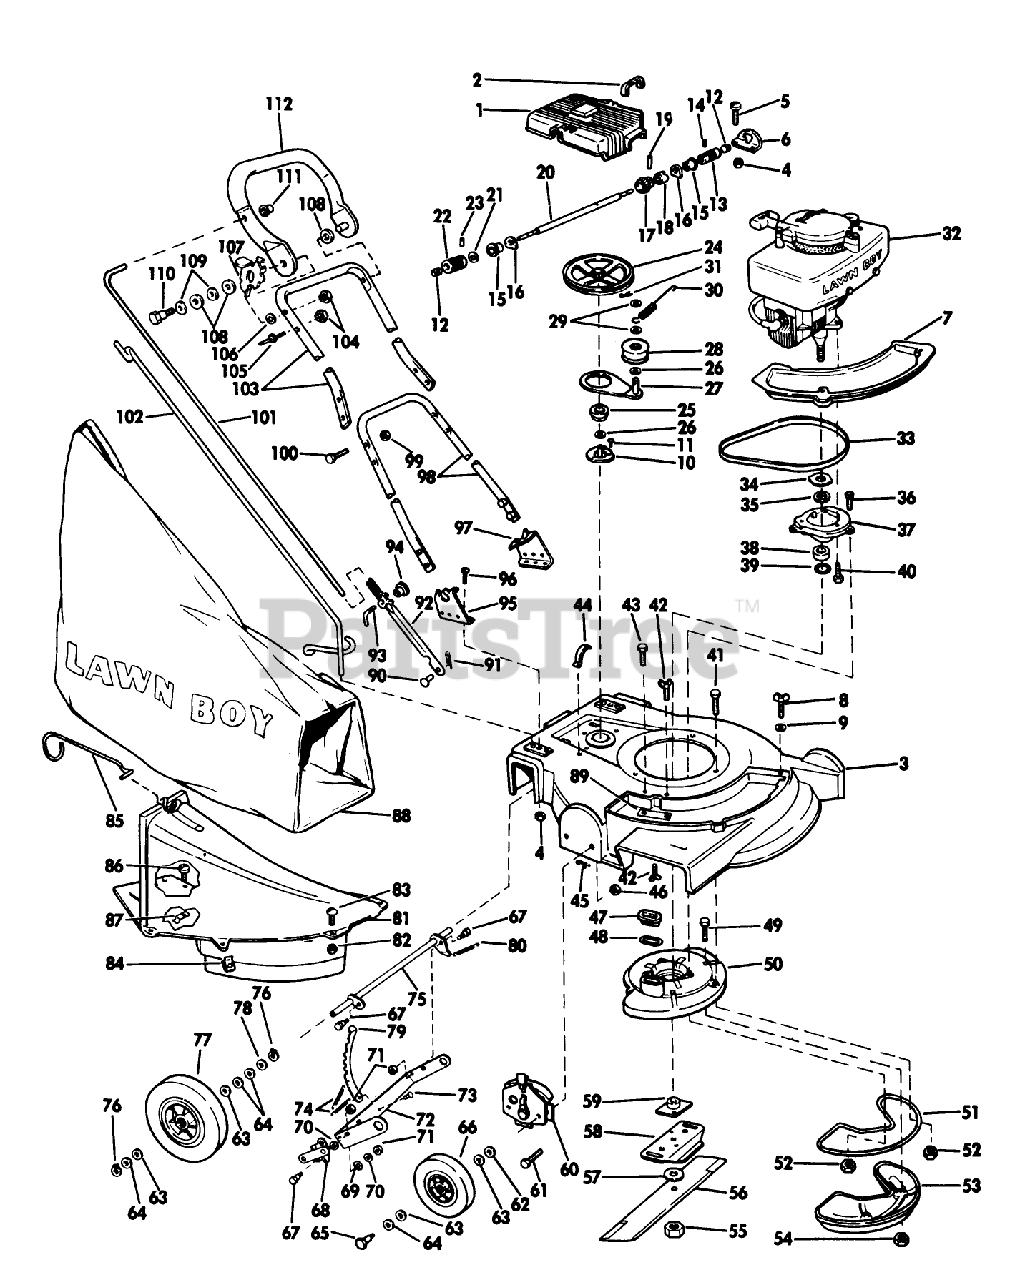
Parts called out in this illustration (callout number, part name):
12	GREASE PLUG
24	PULLEY&OILER FELT (13)
48	GASKET S
54	LOCKNUT E
55	NUT-BLADE
59	PLATE AND COLLAR ASM
62	WASHER WROUGHT
64	SPACER
65	BOLT WHEEL
67	BOLT RB&W
70	WASHER S
71	STOP NUT
76	RETAINING RING
81	Chute Skirt Assembly (Includes Hardware)
84	SPEED NUT ARDEN
88	89802 LB WHOLE GOODS
96	SCREW S
108	WASHER M
110	BOLT PIONEER
